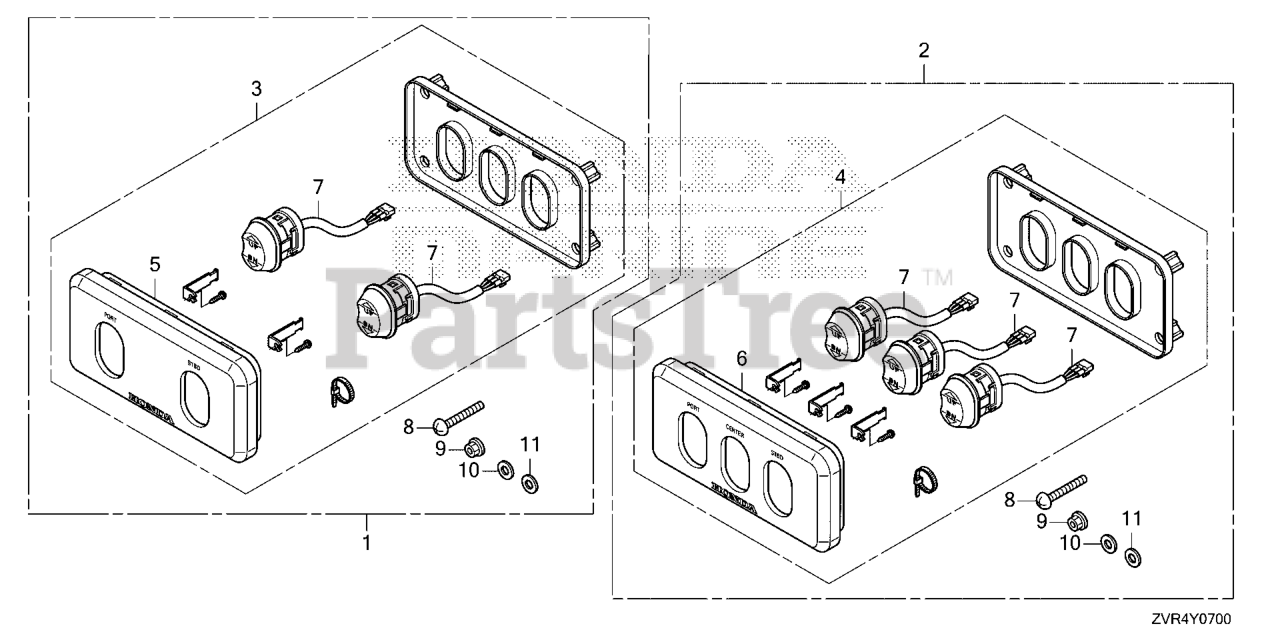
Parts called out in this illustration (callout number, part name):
1	PANEL KIT, POWER TRIM-TILT SWITCH (TWIN)
2	PANEL KIT, PTT SW
3	PANEL ASSY., POWER TRIM-TILT SWITCH (TWIN)
4	PANEL ASSY., POWER TRIM-TILT SWITCH (TRIPLE)
5	PANEL, POWER TRIM-TILT SWITCH (TWIN)
6	PANEL, POWER TRIM-TILT SWITCH (TRIPLE)
7	SWITCH ASSY., POWER TILT
8	SCREW, PAN (5X40) DUAL QTY = (8) (SINGLE)
9	NUT, FLANGE (5MM)
10	WASHER, PLAIN (5MM)
11	WASHER, SPG (5MM)
